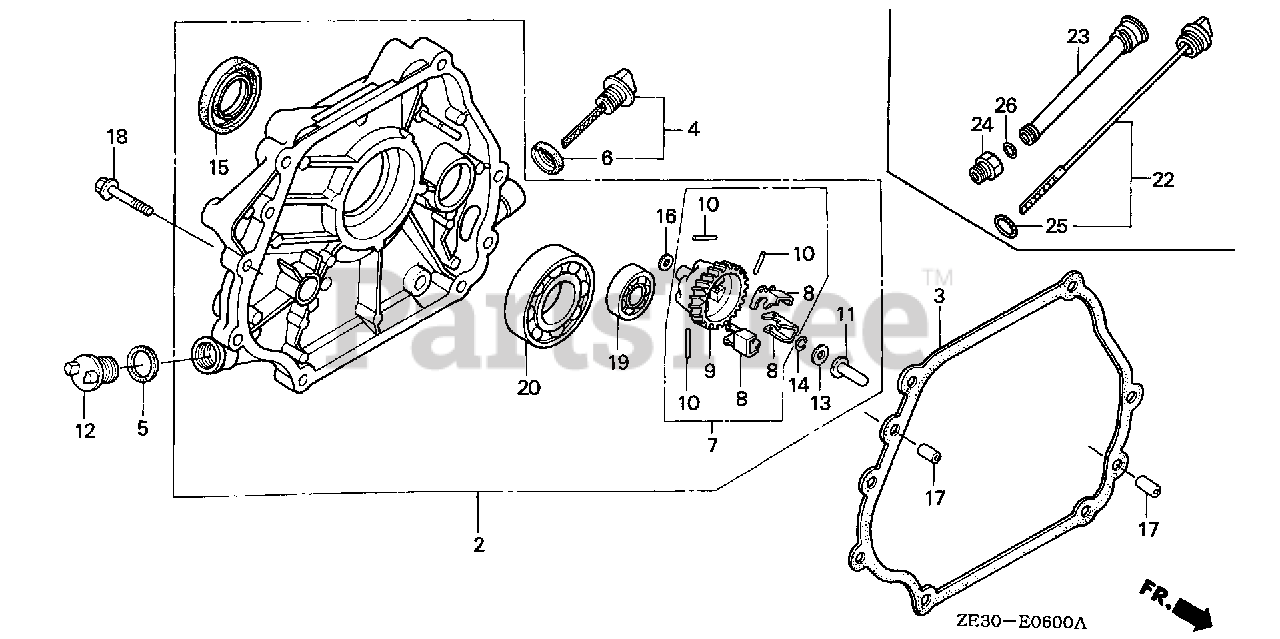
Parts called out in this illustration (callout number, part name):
2	COVER ASSY., CRANKCASE
2	COVER ASSY., CRANKCASE (NOT AVAILABLE)
3	GASKET, CASE COVER
5	GASKET, OIL FILLER CAP
7	GOVERNOR ASSY.
7	GOVERNOR ASSY. (NOT AVAILABLE)
8	WEIGHT, GOVERNOR
9	HOLDER, GOVERNOR WEIGHT
10	PIN, GOVERNOR WEIGHT
11	SLIDER, GOVERNOR
12	CAP, OIL FILLER
13	WASHER (6X16)
14	CLIP, GOVERNOR HOLDER
15	OIL SEAL (35X52X8)
16	WASHER, PLAIN (6MM)
17	PIN, DOWEL (8X12)
17	PIN A, DOWEL (8X12)
18	BOLT, FLANGE (8X40)
19	BEARING, RADIAL BALL (6202)
20	BEARING, RADIAL BALL (6207)
22	GAUGE ASSY., LEVEL
23	PIPE, OIL FILLER
24	BOLT, JOINT (NOT AVAILABLE)
25	O-RING (26X2.7)
26	O-RING (15X2.5)
